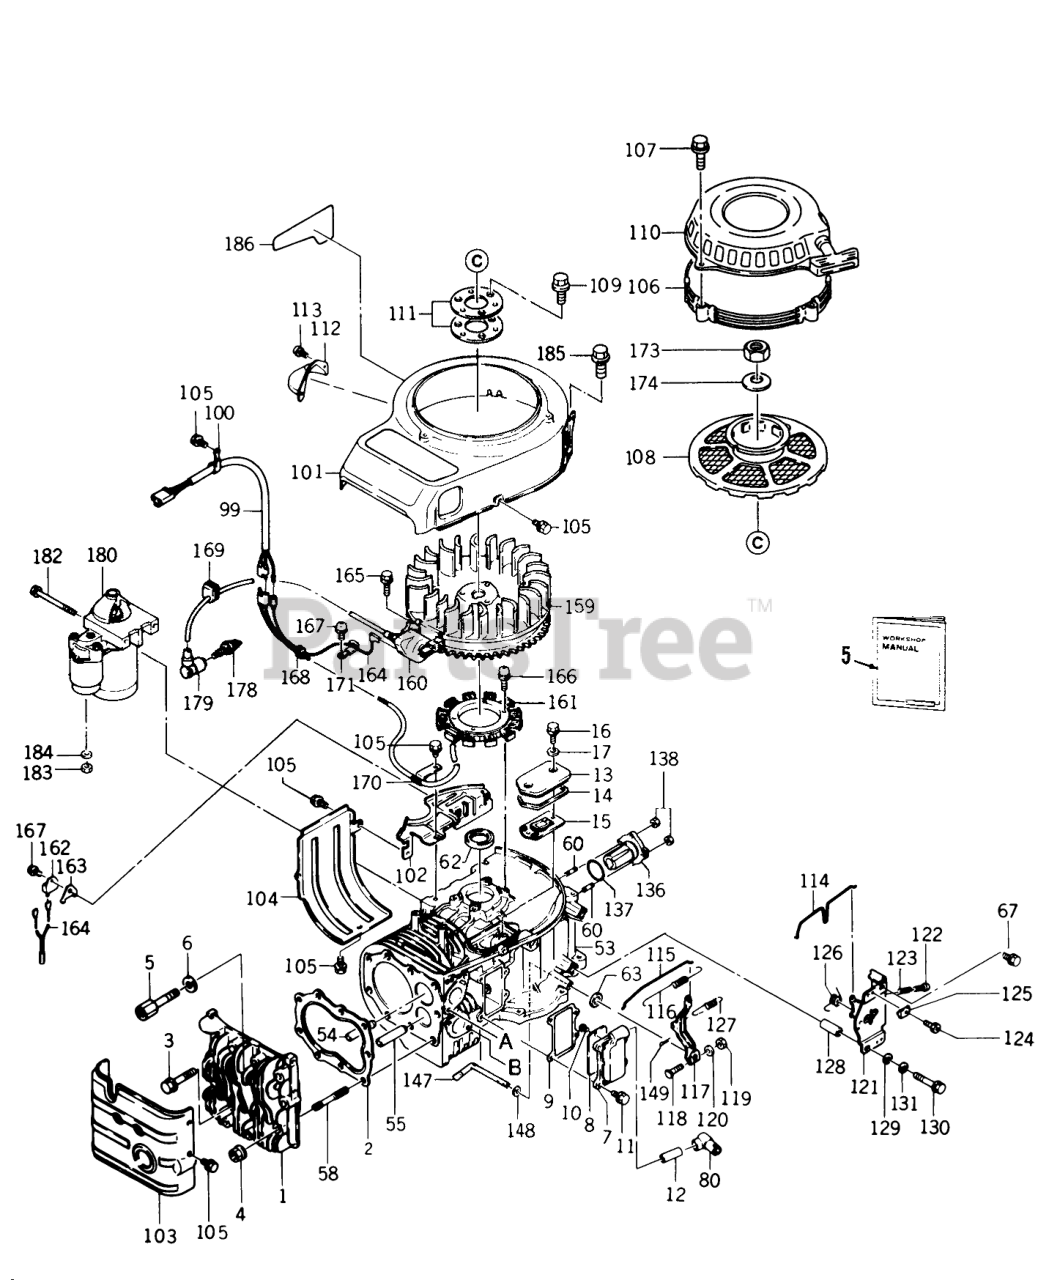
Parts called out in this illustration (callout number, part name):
1	Cylinder Head
2	GASKET-HEAD
3	BOLT 10X55
5	Kawasaki FB460V Workshop Manual
7	COVER
8	COVER
9	GASKET
10	SCREW
11	Bolt
13	COVER
14	GASKET
15	BREATHER
17	GASKET-OIL GAUGE
53	Crankcase Complete (includes items 54 & 55)
54	GUIDE-VALVE
55	VALVE-GUIDE
62	SEAL OIL
63	SEAL-OIL, VC (6X10X2.5)
67	BOLT-FLANGED
80	JOINT
100	CLAMP
101	Fan Housing
102	HOUSING-FAN
103	SHROUD
104	Shroud
105	BOLT-FLANGED
106	GUARD
107	Bolt 6x35
108	PULLEY
109	BOLT-FLANGED
110	Recoil Starter Complete-see section 9-8 for complete breakdown
112	COVER
113	SCREW 4X8
116	SPRING
117	GOVERNOR ARM COMP
118	Bolt
119	NUT 6MM
120	Washer
121	Control Panel Assy (includes items 122, 123, 124, 125 & 126)
122	SCREW PAN HEAD 4X25
123	SPRING
125	CLAMP
126	SPRING
127	Spring
128	COLLAR
129	WASHER, CLUTCH
130	BOLT 6X50
131	WASHER-SPRING 6MM
136	SHAFT
137	O-RING
138	Nut
147	ARM-GOVERNOR
148	WASHER-PLAIN 6MM
149	Pin
159	FLYWHEEL ASSY
160	IGNITION COIL
161	COIL-CHARGING
162	IGNITER
163	BRACKET
164	WIRE-LEAD
166	SCREW-PAN-WP-CROS
167	SCREW 4X8
168	GROMMET
169	GROMMET
170	CLAMP
171	CLAMP
173	NUT 18MM
174	WASHER
178	Plug-Spark
179	CAP-SPARKPLUG
180	STARTER ASSY ELECTRI
183	NUT-8M/M
184	WASHER 5/16 SAE
185	Bolt
